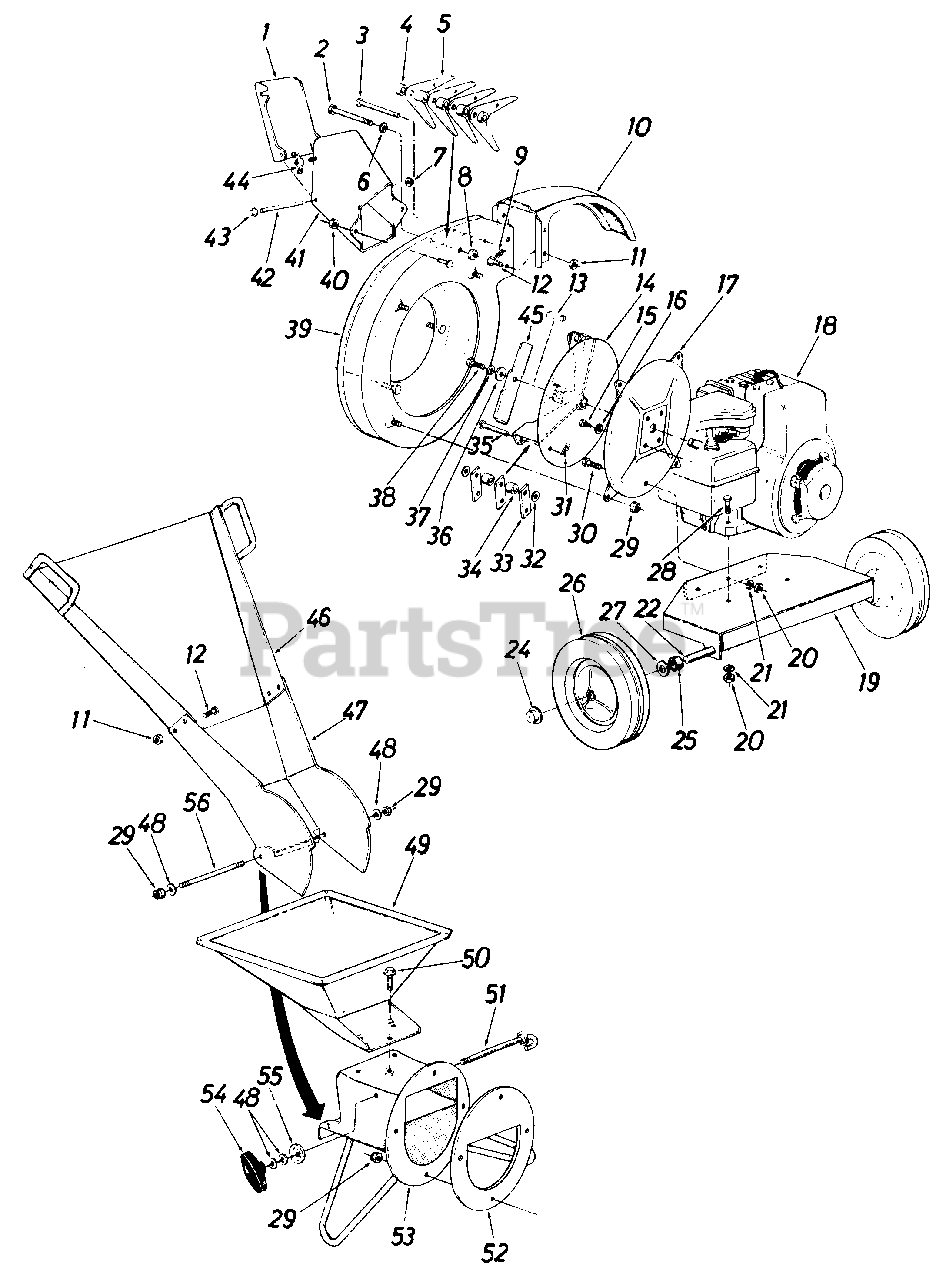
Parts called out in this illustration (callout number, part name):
1	Door-Chip-It
2	Hex Bolt 1/2-20 x 4.50" Lg.
3	Clevis Pin
4	Flail Spacer 7/32" Lg.
5	Cutting Finger
6	L.-Wash. 1/2" Scr.
7	Palnut 3/16" Dia.
8	Hex Jam Nut 1/2-20 Thd.
9	Cotter Pin 3/32" Dia. x 3/4" Lg.
10	Chute Deflector
11	L.-Nut 1/4-20 Thd.
12	Hex Bolt 1/4-20 x .50" Lg.
13	Sq. Key 1/4" x 2.00" Lg.
14	Impeller Assembly
15	Hex Bolt 5/16-24 x 3/4" Lg.
16	L-Wash. 5/16" Scr.
17	Hopper to Engine Mtg. Plate
18	Engine
19	Engine Mounting Plate
20	Hex Nut 5/16-24 Thd.
21	L-Wash. 5/16" Scr.
22	Shaft 1/2" x 18 7/8" Lg.
26	Wheel Ass'y. - Comp.
27	Fl-Wash. .50" I.D.
28	Hex Bolt 5/16-24 x 1.50" Lg.
29	Elastic Stopnut 5/16-18 Thd.
30	Hex Bolt 5/16-24 x .62" Lg.
31	Cotter Pin 1/8" Dia. x 1.00" Lg. (Special)
32	Fl-Wash. .531" I.D. x .937 O.D. x .09
33	Flail
34	Flail Spacer 23/32" Lg.
35	Clevis Pin .50" Dia. x 3.0" Lg.
36	Fl.-Wash. .406" I.D. x 1.25" O.D. Hdn.
37	L.-Wash. 3/8" Scr. H.D.
38	Hex Bolt 3/8-24 x 2.00" Lg. H.T.
41	Upper Guide Extension Ass'y.
42	Hinge Pin
43	Palnut 3/16" Dia.
44	Wing Nut Elastic 1/4-20 Thd.
47	Guide Extension
48	Fl-Wash. 5/16" Scr.
49	Hopper Assembly
50	Hex Wash. Hd. Self-Tap Scr. 5/16-18 x .50" Lg.
51	Clamp Rod Assembly
52	Back-up Plate
53	Inlet Guide Assembly
54	Knob Ass'y.
55	Stop Washer
56	Chute Pivot Rod
